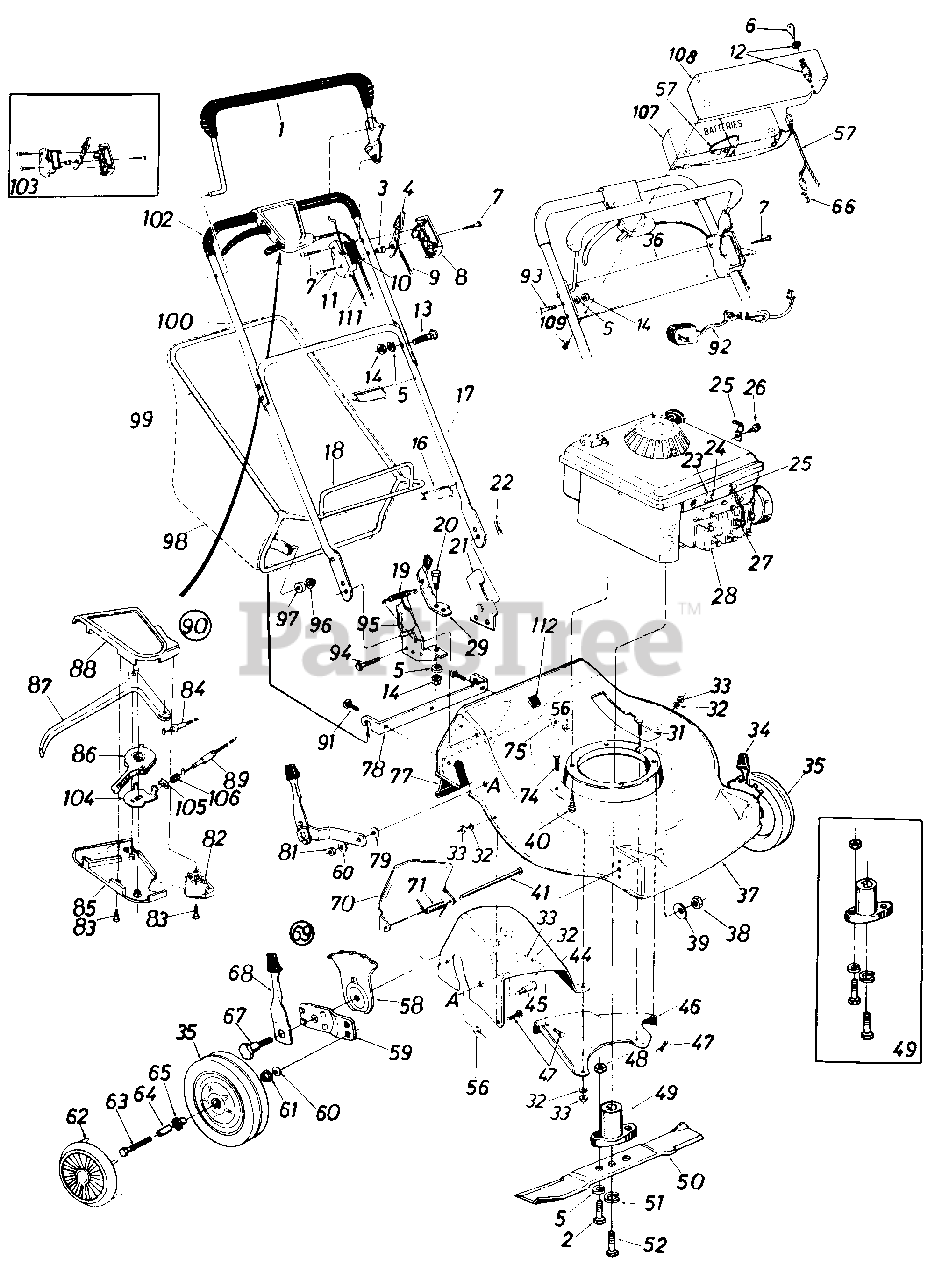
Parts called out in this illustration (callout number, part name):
1	L.H. Bail Ass'y.
2	Hex Bolt 5/16-24 x 1.00" Lg. (Grade 5)
3	Control Disc Pin
4	Throttle Control Lever
5	L-Wash. 5/16" I.D.
6	Ignition Key
7	Truss Mach. Hi-B Tap Scr. #12 x 1.50" Lg.
8	Control Panel Half
9	Throttle Control Wire-58"
10	Control Label
11	Clutch Panel Half
12	Ignition Switch
13	Carr. Bolt 5/16-18 x 1.75"
14	Hex Nut 5/16-18 Thd.*
16	Cable Tie
17	Lower Handle
20	Shld. Bolt .437" Dia. x .162
21	Handle Brkt. Ass'y.-L.H.
22	Hairpin Cotter 5/16" Dia.
23	Casing Clamp
24	Hex B-Tap Scr. #10 x .62"
25	Cable Clip
26	Hex B-Tap Scr. #10 x .38"
27	Spark Plug Insulator
28	Engine
29	Lock Lever w/Knob
31	Hex TT-Tap Scr. 1/4-20 x .75" Lg.
32	L-Wash. 1/4" I.D.
33	Hex Nut 1/4-20 Thd.
34	Height Adj. Ass'y.-L.H.
35	Front Wheel Ass'y. Comp.
36	Lower Battery Tray
39	Bell-Wash. .39" I.D. x 1.38"
40	Hex Wash. Hd. TT-Tap Scr. 3/8-16 x 1.0" Lg.
41	Hinge Pin
44	Rear Chute-R.H.
45	Shld. Bolt.500" Dia.
46	Rear Baffle-L.H.
47	Carr. Bolt 1/4-20 x .50" Lg.
48	Hex Nut 5/16-24 Thd.
49	Blade Adapter Kit
50	22" Blade
51	L-Wash. 3/8" I.D. H.D.
52	Hex Bolt 3/8-24 x 2.25" Lg. (Grade 5)
56	Hex Sems Nut 1/4-20 Thd.
57	Wire Harness
58	Height Adj. Plate
59	Wheel Pivot Bar
60	Bell-Wash. .40" I.D. x .88"
61	Flg. Ball Brg. 3/8" I.D.
62	Plastic Hub Cap
63	Hex Bolt 3/8-16 x 1.75" Lg.
64	Spacer.375" I.D.
65	Flg. Ball Brg. 1/2" I.D.
66	Plug
67	Shld. Bolt .50" Dia. x .430
68	Spring Lever Ass'y. w/ Knob
69	Height Adj. Ass'y.-R.H.
70	Chute Door
71	Torsion Spring
74	Hex Bolt 1/4-20 x .88" Lg.
75	Fl-Wash. .285" I.D. x 1.25"
77	Rear Flap
78	Grass Catcher Hitch Brkt.
79	Bell-Wash. .40" I.D. x 1.13"
81	Hex Jam Nut 3/8-16 Thd.
82	Cable Mounting Cap
83	Flat "C"-Sunk Hd. Tap Scr. #10 x .75" Lg.
84	S.P. Cable x 53" Lg.
85	3-Sp. S.P. Control-Lower Cover
86	Shimano 3-Sp. Shift Lever
87	Control Lever
88	3-Sp. S.P. Control-Upper Cover
89	Shimano 3-Sp. Solid ShiftCable
90	Clutch Control Hsg. Comp.
91	Carr. Bolt 1/4-20 x .75" Lg.
92	Battery Charger
93	Carr. Bolt 5/16-18 x 1.38"
94	Hex Bolt 1/4-28 x .75" Lg.
95	Handle Brkt. Ass'y.-R.H.
96	Push Nut 3/8" Rod
97	Plastic Roller
98	Grass Bag
99	Catcher Upper Frame
100	Upper Handle
103	Control Housing Comp.
104	Shimano 3-Sp. Shift Lever Brkt.
105	Shimano 3-Sp. Cable Spring Brkt.
106	Shimano 3-Sp. Cable Mounting Spring
107	Battery Pack
108	Battery Tray
109	Truss Mach. Hi-Riser Tap Scr. 1 " Lg.
111	Clutch Control Cable 43"
8367-000-6	Hardware Pack
